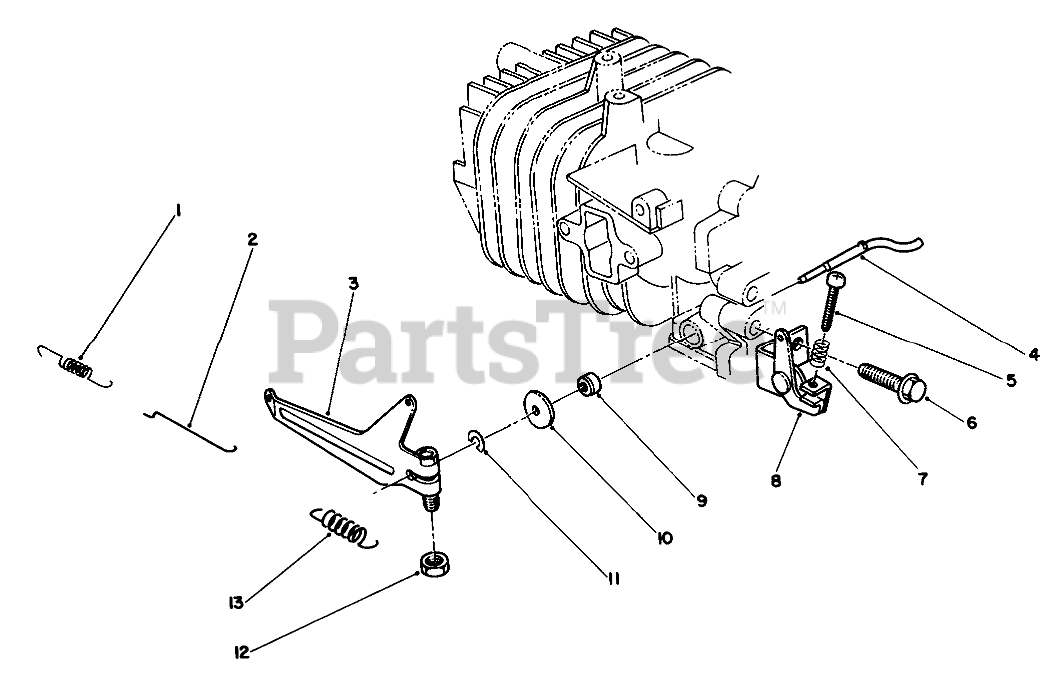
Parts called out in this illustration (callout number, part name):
1	CARB SPRING
2	CARB ROD
3	GOVERNOR ARM
4	SHAFT
5	SCREW
7	SPRING
8	GOV SPR BRKT
9	SEAL-OIL
10	WASHER
11	E-RING
13	GOV SPRING
